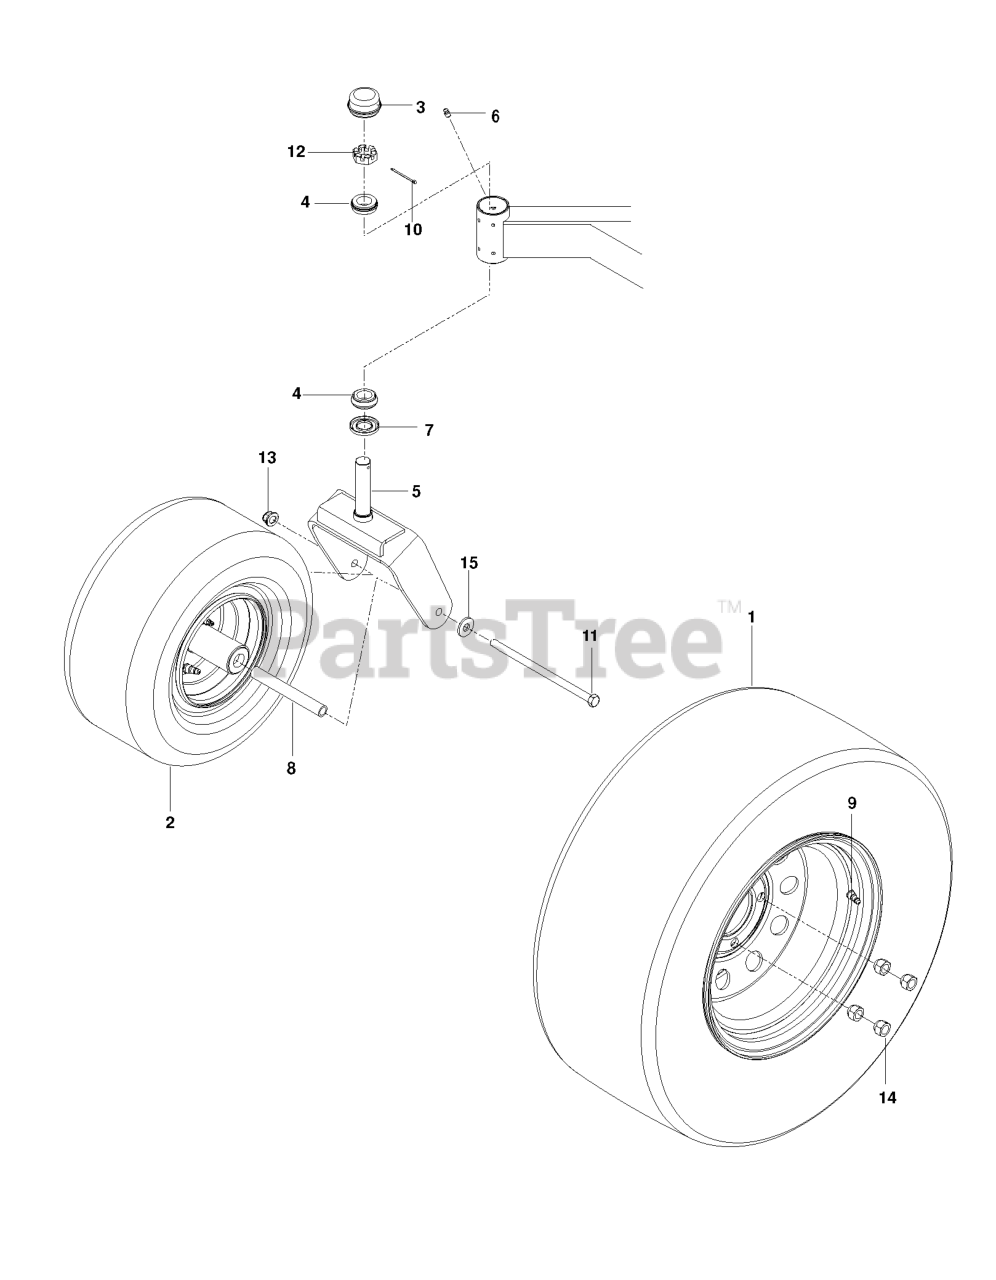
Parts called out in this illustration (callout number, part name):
1	WHEEL.ASSEM.22X10-10.SILVE.ZTR
2	TIRE.ASSEM.CASTER.13X6.5-6.SIL
3	GREASE CAP
4	TAPERED ROLLER BRG
5	YOKE.CASTER.ORANGE
6	ZERK
8	SPACER, PIVOT
9	VALVE STEM TR-412
10	COTTER PIN 1/8 X 2
11	HEX SCREW 1/2-13 X 9.5 GR5
12	NUT 1"C HEX SLOTTED
13	NUT, 1/2-13 HEX FLG NYLOC ZD
14	LUG NUT 1/2F
15	WASH USS FLAT 1/2
